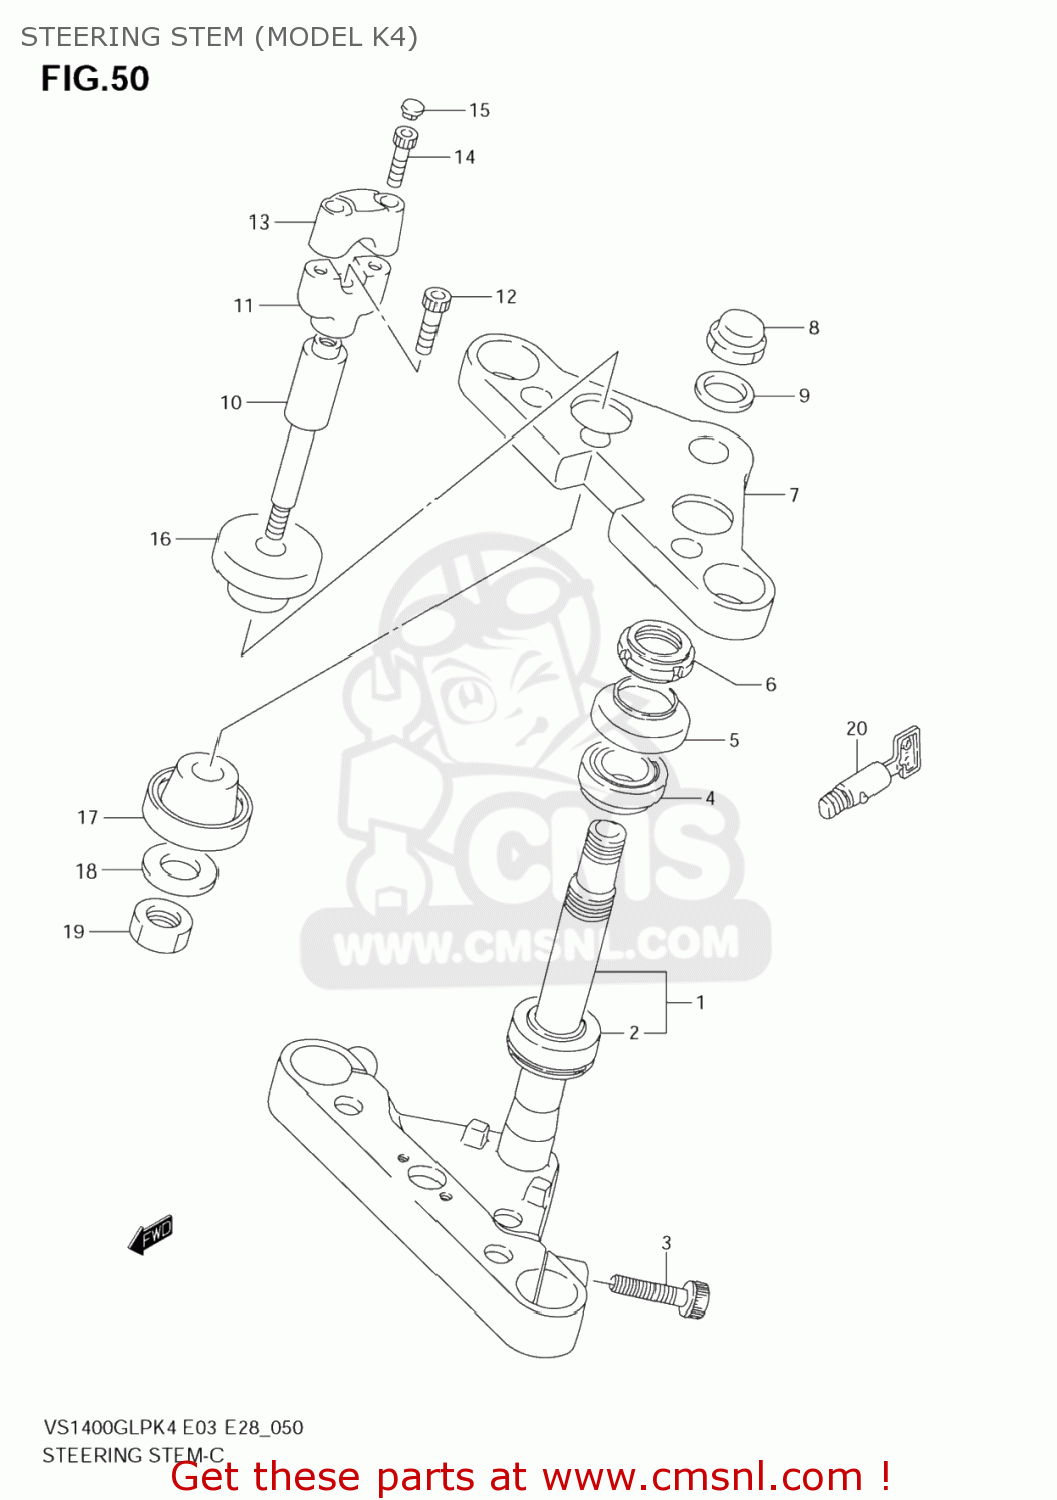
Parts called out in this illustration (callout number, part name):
1	STEM,STEERING
2	BEARING(30X55X17)
3	BOLT
4	BEARING(25X47X15)
5	SEAL,STEERING UPR DUST
6	NUT,STEERING STEM(25X44X10)
7	BRACKET,FR FORK UPR
8	NUT,CAP
9	WASHER(22.5X32X1.6)
10	STAY,HANDLE
11	HOLDER,HANDLE LWR
12	BOLT
13	HOLDER,HANDLE UPR
14	BOLT
15	CAP(OD:14.5)
16	DAMPER,RUBBER
17	CUSHION,RUBBER UNDER
18	WASHER
19	NUT
20	LOCK SET,STEERING
